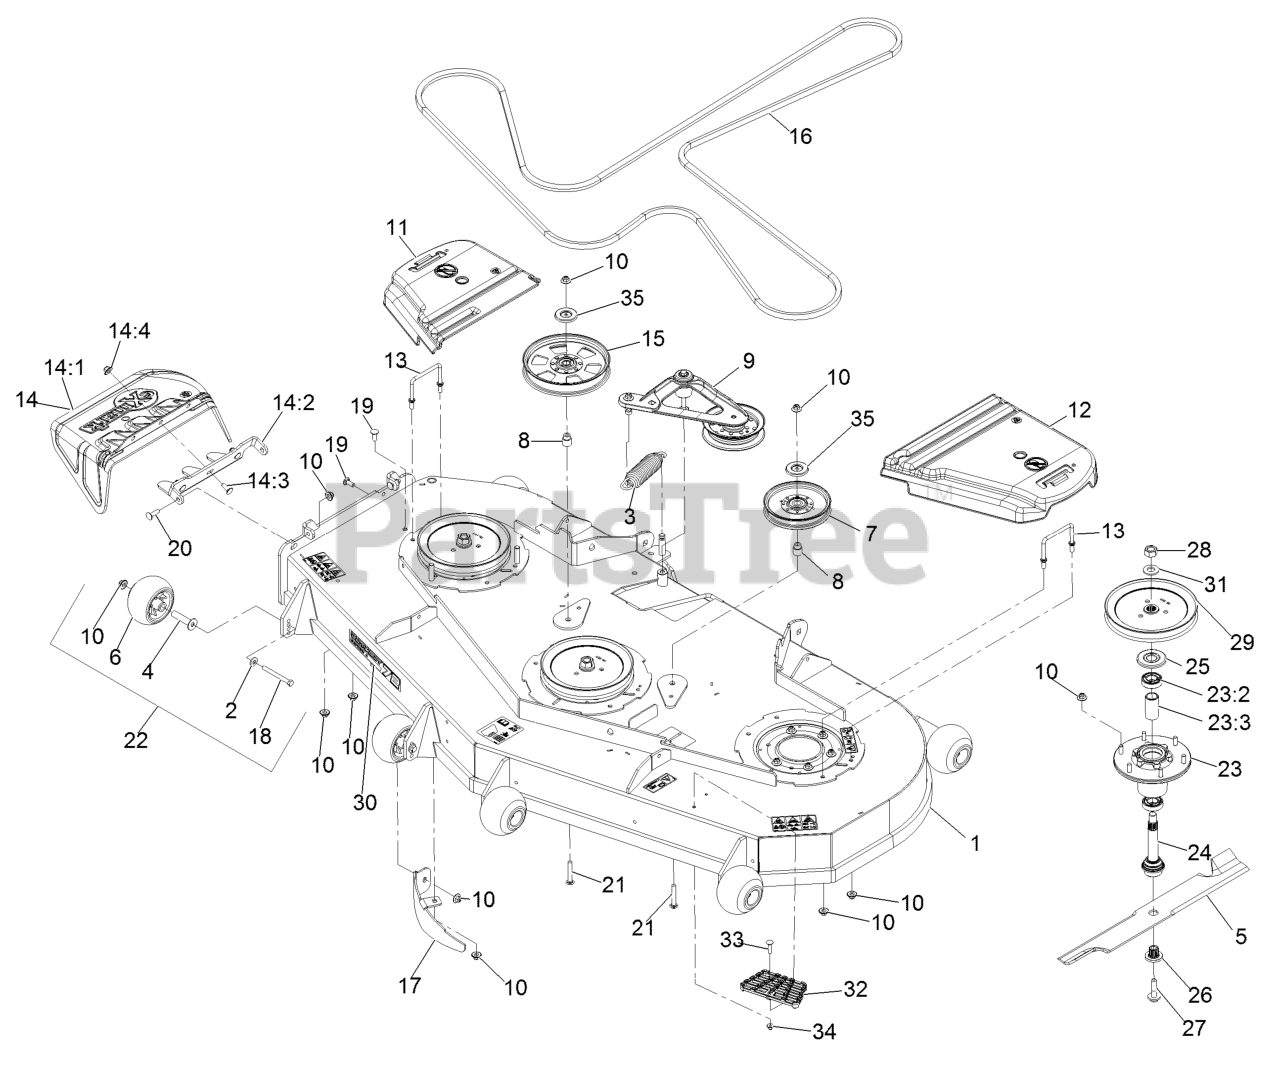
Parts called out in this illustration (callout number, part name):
1	ASM,DECK W/DECALS 724
2	WASHER-BELLEVILLE
3	SPRING-EXTENSION
4	AXLE, ROLLER
6	ROLLER-SCALP, ANTI
7	IDLER-PULLEY
8	BUSHING-IDLER
9	DECK IDLER ASM
10	Nut-Nyloc 3/8-16 Flg
11	COVER-BELT, RH
12	COVER-BELT, LH
13	WIREFORM-COVER
14	ASM,DISCHARGE CHUTE
14:1	CHUTE,DISCHARGE
14:2	BRACKET,DISCHARGE CHUTE
14:3	SCREW-CARR
14:4	Nut-Nyloc 3/8-16 Flg
15	PULLEY-IDLER, FLAT
16	BELT-V
17	BAFFLE-DOGLEG, LZ72
18	SCREW-HH 3/8-16 X 3 3/4 GR 8
19	SCREW-CARR
20	Bolt-Carriage 3/8-16 X 1 1/4
21	SCREW-CARR
22	KIT, ANTI-SCALP ROLLER
23	ASM-CUTTER HSG WITH BEARINGS
23:2	BEARING-BALL
23:3	SPACER-BEARING
24	ASM-SPINDLE AND SEAL
25	GUARD,BEARING TOP .989
26	BUSHING,SPLINED
27	SCREW,SEMS 1/2-20 X 2.19
28	NUT-HEX
29	SHEAVE,BLADE DRIVE 8.74
30	DECAL, 724
32	STEP-DECK
33	Bolt-Carriage 5/16-18 X 1 1/4
34	NUT-HF, NI
35	SHIELD-DUST
